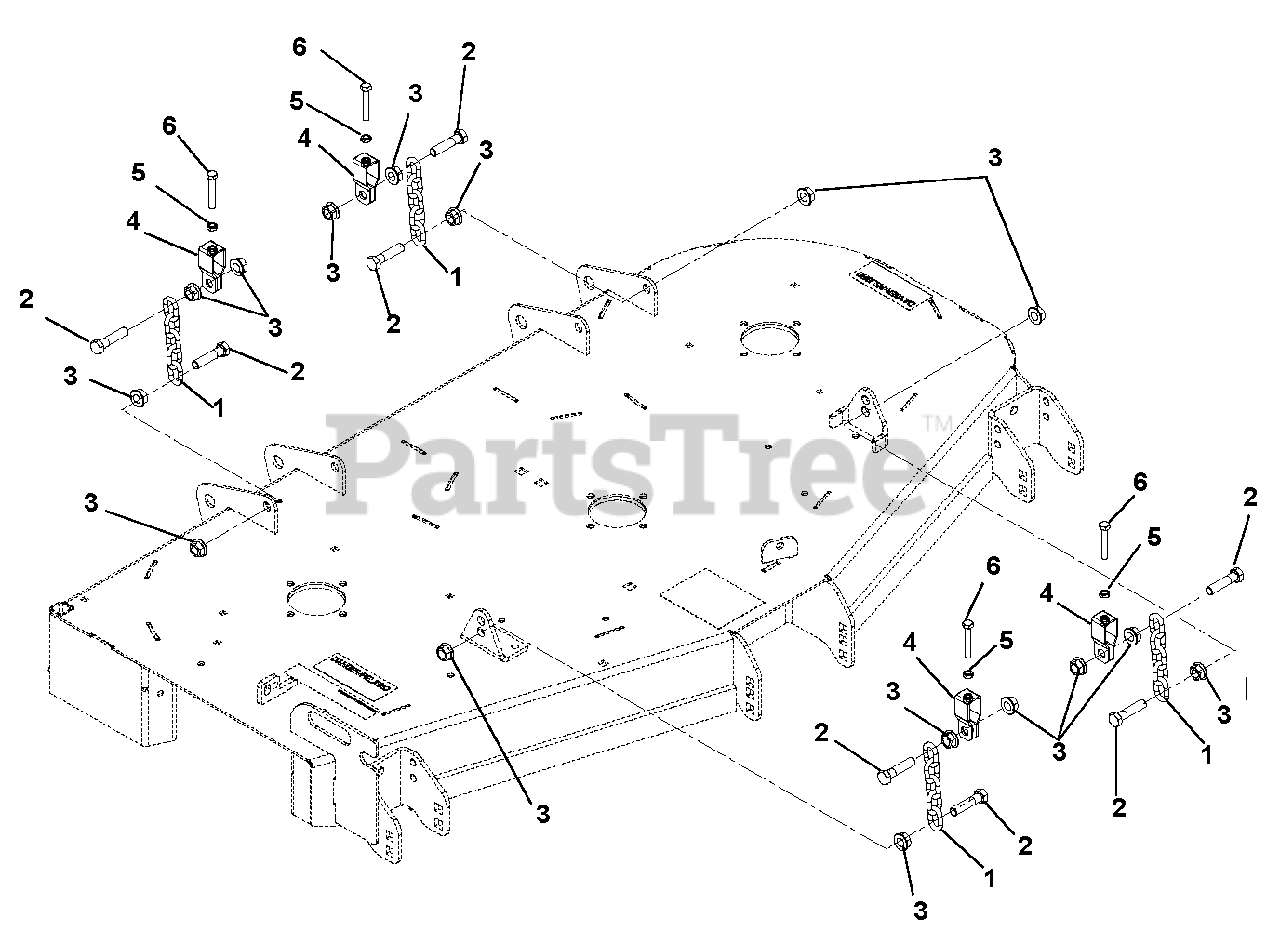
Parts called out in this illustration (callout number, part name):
1	Chain, Link
2	Bolt, Hex M12-1.75 x 50 Class 8.8
3	Nut, Spin Lock, Flange M12-1.75
4	Bracket, Deck Leveling
5	Nut, Jam .312-18
6	Bolt, Hex .312-18 x 2.00 FTH Grade 5
